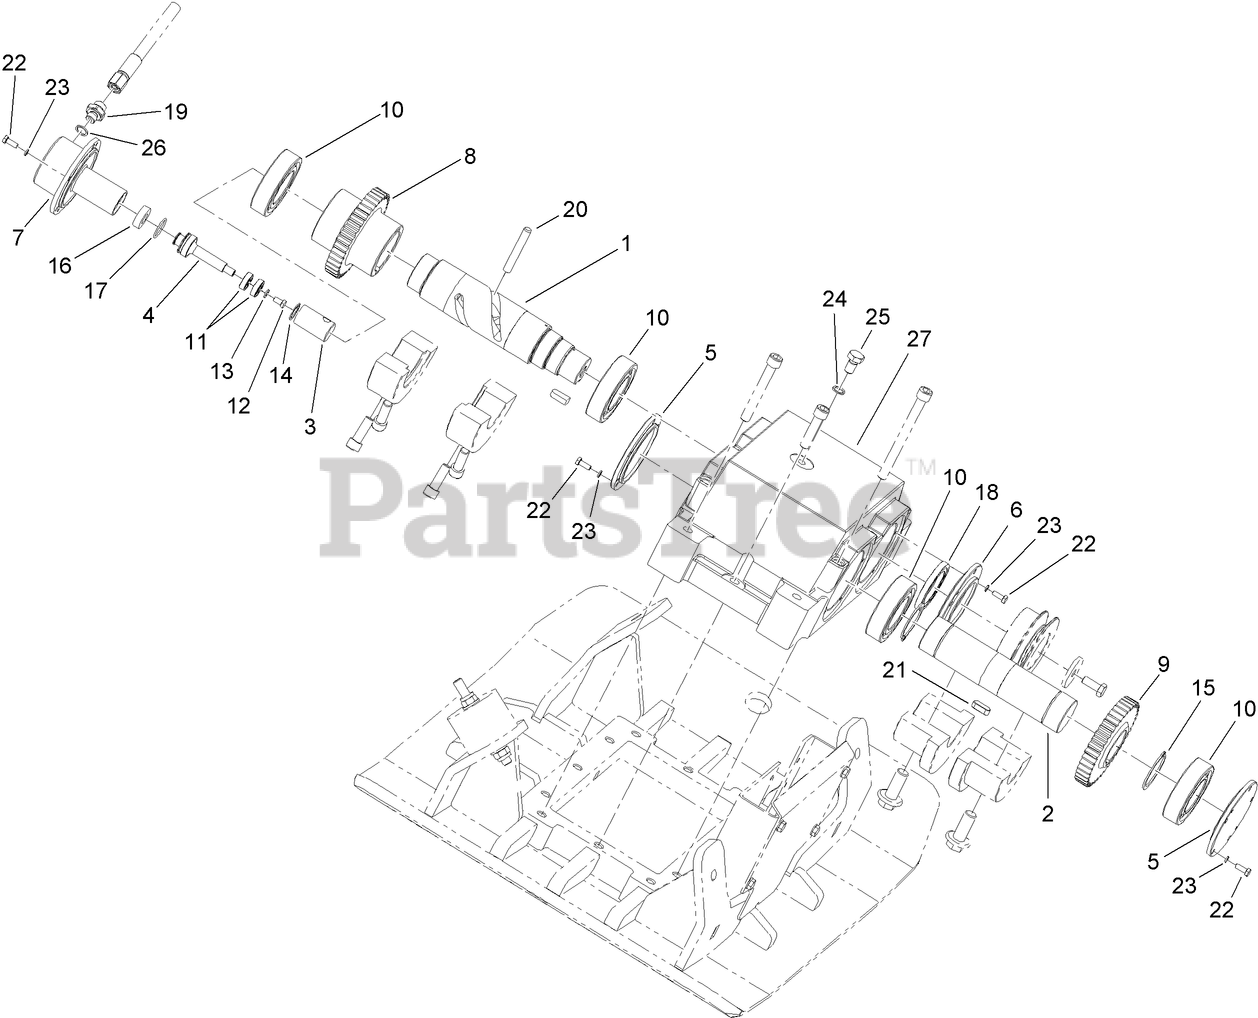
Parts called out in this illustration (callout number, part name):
1	SHAFT-HOLLOW
3	SLIDE-VALVE
4	PISTION
10	BEARING
11	BEARING
13	WASHER
16	SPACER
17	O-RING
18	SPACER
19	SOCKET
23	WASHER
24	RING-SEALING
26	RING-SEALING
27	HOUSING
